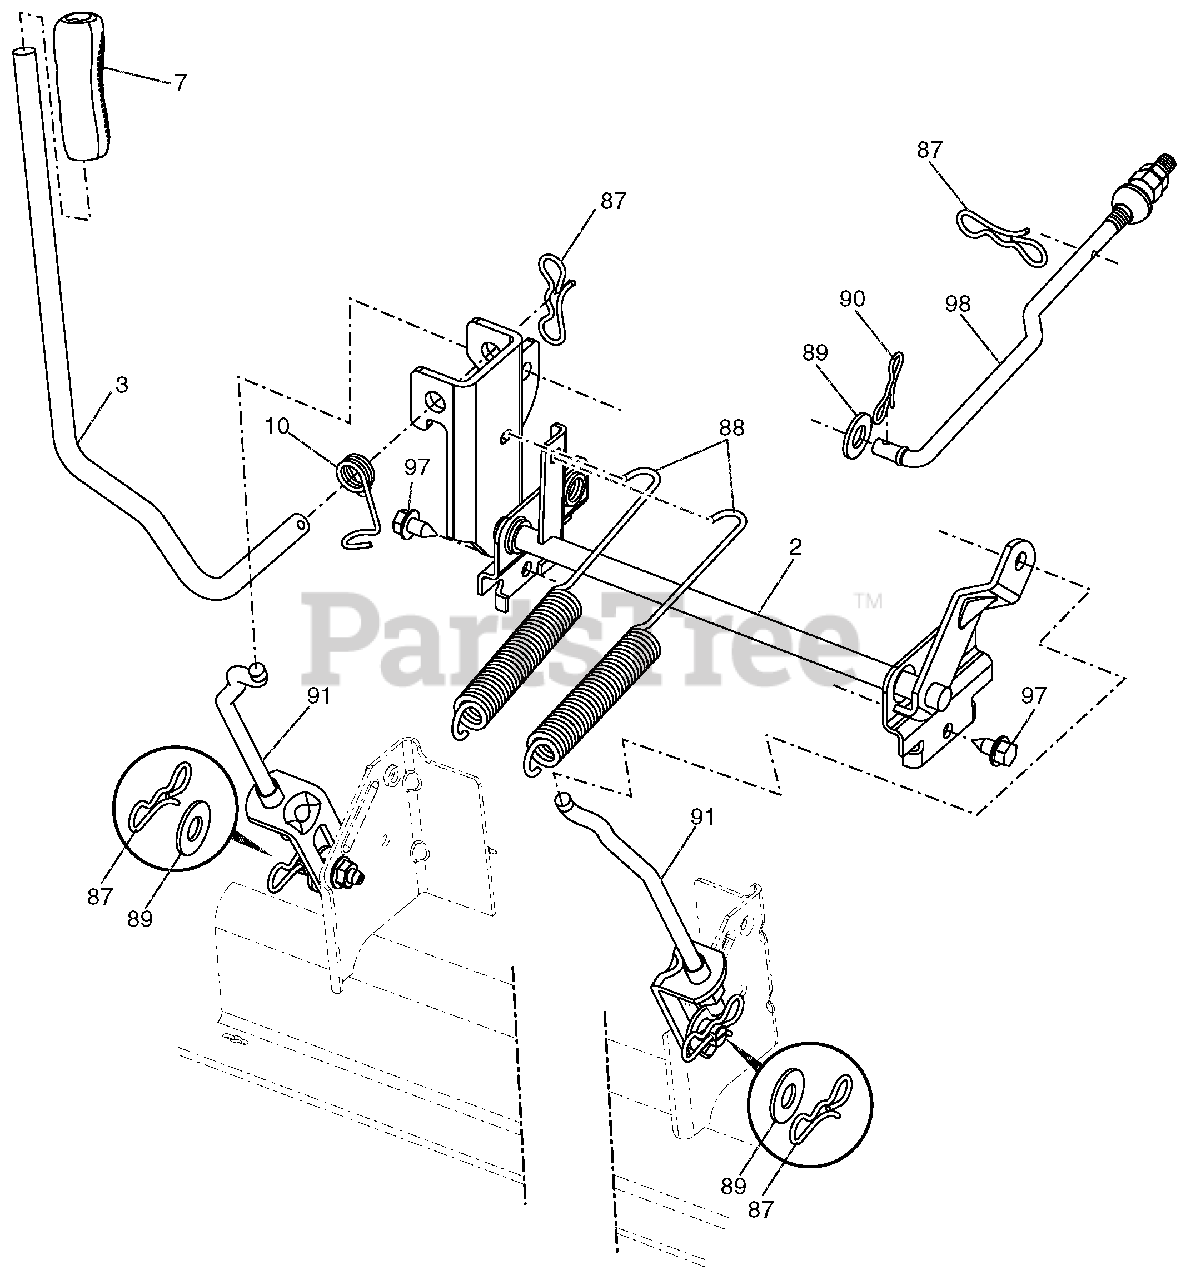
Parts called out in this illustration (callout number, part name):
2	SHAFT ASM.LIFT.CROSS.HD.
3	LEVER.LIFT.HANDLE.LT
7	GRIP.LEVER..5625 ID.BLACK 428
10	SPRING.TORSION.HANDLE.LIFT
87	PIN.COTTER.7/16.BOW TIE LOCK
88	SPRING.LIFT ASSIST
89	WASHER.17/32 X 1-3/16 X 12 GA.
90	PIN.COTTER.5/16.BOW TIE LOCK
91	LINK ASM.LIFT.54"TG
97	SCREW.HEXWSH THDR3/8-16X3/4.BL
98	LINK ASM.SUSP.FRONT.MWR.10.5
100	NUT.CENTERLOCK.3/8-16 UNC.
